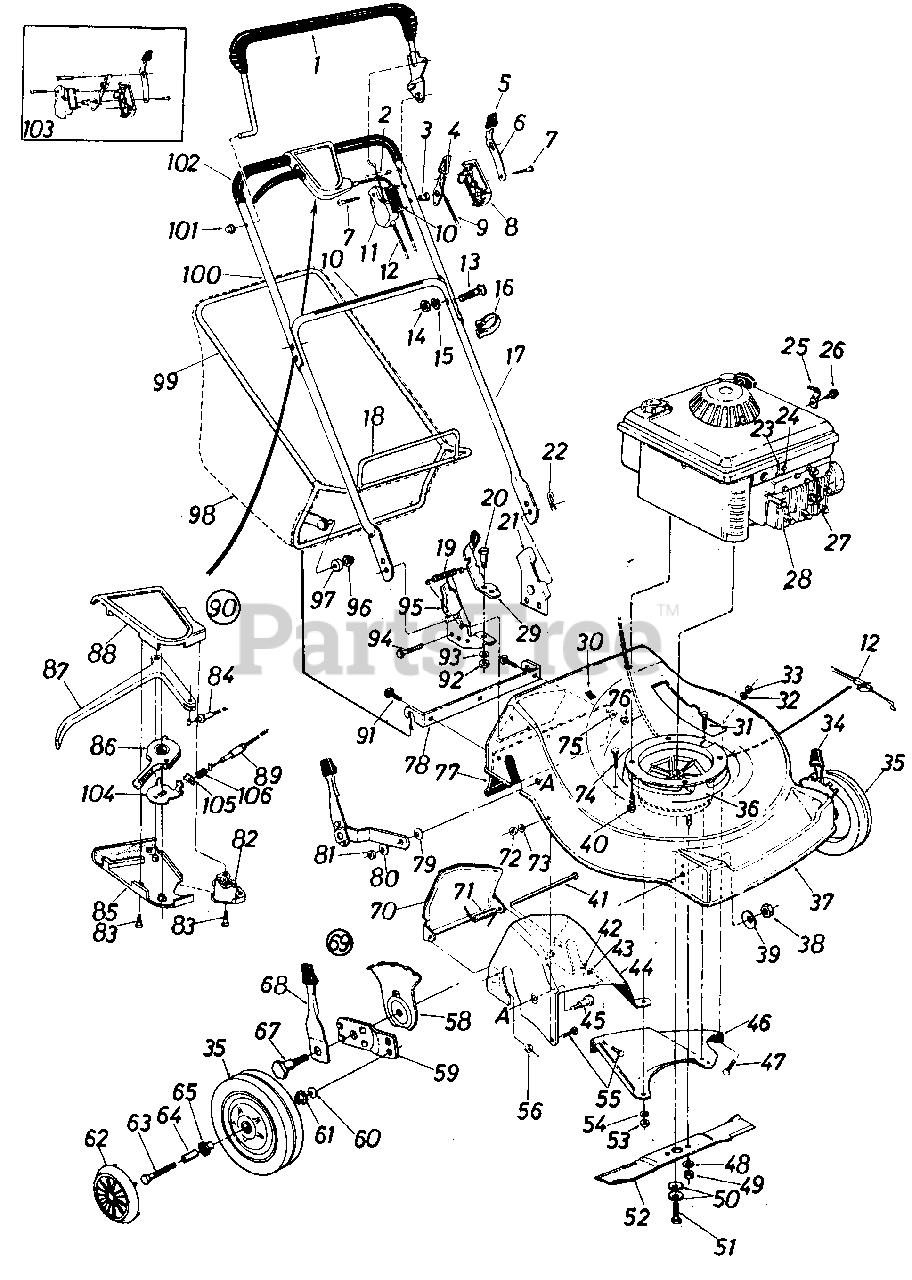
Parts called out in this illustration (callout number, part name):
1	L.H. Bail Ass'y.
2	Lock Pin
3	Control Disc Pin
4	Throttle Control Lever
5	Spring Lever Knob
6	Lockout Spring
7	Truss Mach. Hi-B Tap Scr. #12 x 1.50" Lg.
8	Control Panel Half
9	Throttle Control Wire- 58" Lg.
10	Control Labels
11	Clutch Panel Half
12	Clutch Cable 46" Lg.-Black
13	Curve Carr. Bolt 5/16-18 x 1.38" Lg.
14	Hex Nut 5/16-18 Thd.
15	L-Wash. 5/16" I.D.*
16	Cable Tie
17	Lower Handle (Chrome)
20	Shld. Bolt .437" Dia. x .162
21	Handle Bracket Ass'y.- L.H .
22	Hairpin Cotter 5/16" Dia.
23	Hex "B"-Tap Scr. #10 x .38" Lg.
24	Casing Clamp
25	Cable Clip
26	Hex Sems Scr. #10-32 x .62" Lg.
27	Spark Plug Insulator
28	Engine
29	Grass Catcher Lock Lever w/Knob
31	Hex TT-Tap Scr. 1/4-20 x .75" Lg.
32	L-Wash 1/4" k D
33	Hex Nut 1/4-20 Thd.
34	Height Adj. Ass'y.-L.H .
35	Front Wheel Ass'y. Comp. 8 x 1.75
36	Blade/Brake Clutch Ass'y.-Comp.
39	Bell-Wash. .39" I.D. x 1.38" O.D.
40	Hex Wash. Hd. TT-Tap Scr. 3/8-16 x 1.0" Lg.
41	Hinge Pin
42	Hex Nut 1/4-20 Thd.
43	L-Wash. 1/4" I.D.
44	Rear Chute-R.H.
45	Shld. Bolt .500" Dia. x .685"
46	Rear Baffle-L H.
47	Carr. Bolt 1/4-20 x .50" Lg.
48	L-Wash. 3/8" I.D.
49	Hex Nut 3/8-24 Thd. (Grade 8)
50	Bell-Wash. .40" I.D. x .88" O.D.
51	Hex Cl-Bolt 3/8-24 x 2.0" Lg. (Grade 8)
52	22" Blade
53	Hex Nut 1/4-20 Thd.
54	L-Wash. 1/4" I.D.
55	Carr. Bolt 1/4-20 x .50" Lg.
56	Hex Sems Nut 1/4-20 Thd.
58	Height Adj. Plate
59	Wheel Pivot Bar
60	Bell-Wash. .40" I.D. x .88" O.D.
61	Flg. Ball Brg. 3/8" I.D.
62	Plastic Hub Cap
63	Hex Bolt 3/8-16 x 1.75" Lg.
64	Spacer .375" I.D. x .505"O.D.
65	Flg. Ball Brg. 1/2" I.D.
67	Shld. Bolt .50" Dia. x .430
68	Spring Lever Ass'y. wlKnob
69	Height Adj. Ass'y.-R.H.
70	Chute Door
71	Torsion Spring
72	Hex Nut 1/4 -20 Thd.
73	L-Wash. 1/4" I.D.
74	Hex Bolt 1/4-20 x .88" Lg.
75	Fl-Wash. .285" I.D. x 1.25"O.D.
76	Hex Sems Nut 1/4-20 Thd.
77	Rear Flap
78	Grass Catcher Hitch Brkt.
79	Bell-Wash. .400" I.D. x 1.13" O.D.
80	Bell-Wash. .400" I.D. x .88" O.D.
81	Hex Jam Nut 3/8-16 Thd.
82	Cable Mounting Cap
83	Flat "C"-Sunk Hd. Tap Scr. #10 x .75" Lg.
84	S.P. Cable x 53" Lg.
85	3-Sp. S.P. Control- Lower Cover
86	Shimano 3-Sp. Shift Lever
87	Control Lever
88	3-Sp. S.P. Control- Upper Cover
89	Shimano 3-Sp. Solid Shift Cable
90	Clutch Control Housing Comp.
91	Carr. Bolt 1/4-20 x .75" Lg.
92	Hex Nut 5/16-18 Thd.
93	L-Wash. 5/16" I.D.
94	Hex L-Wash. Hd. AB-Tap Scr. 1/4" x .62" Lg.
95	Handle Bracket Ass'y.-R.H.
96	Push Nut 3/8" Rod
97	Plastic Roller
98	Grass Bag (Without Flip Top)
99	Catcher Upper Frame
100	Upper Handle (Chrome)
101	Cap Speed Nut
103	Control Housing Comp.
104	Shimano 3-Sp. Shift Lever Brkt.
105	Shimano 3-Sp. Cable Spring Brkt.
106	Shimano 3-Sp. Cable Mounting Spring
